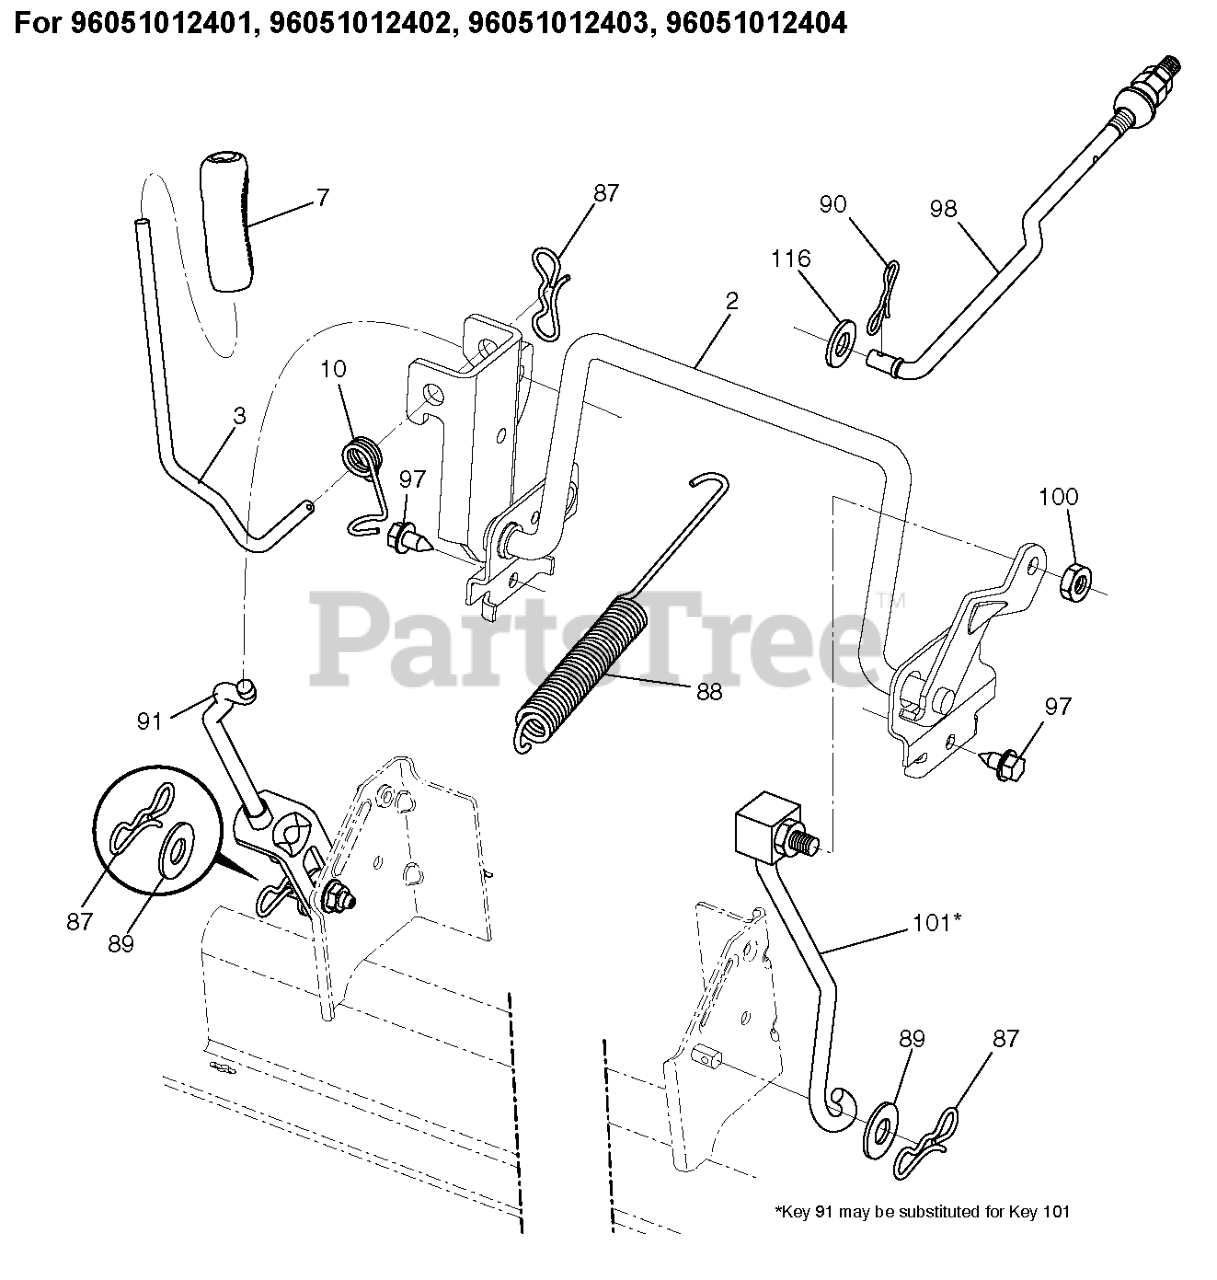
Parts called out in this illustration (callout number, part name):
2	SHAFT LIFT DECK WELD
3	LEVER.LIFT.HANDLE.LT
7	GRIP.HANDLE.LIFT.PVC.BLACK
10	SPRING.TORSION.LIFT.HANDLE
87	PIN.COTTER.7/16.BOW TI.
88	SPRING.DK.LIFT.97/107.TXCRDII
89	WASHER.CLEAR.ZINC
90	PIN.COTTER.5/16.BOW TI
91	LINK.ASM.LIFT.REAR
98	LINK.ASM.SUSP.FRONT.MW
100	LOCKNUT
101	LINK.ASM.LIFT.FIXE.38/42/46"
